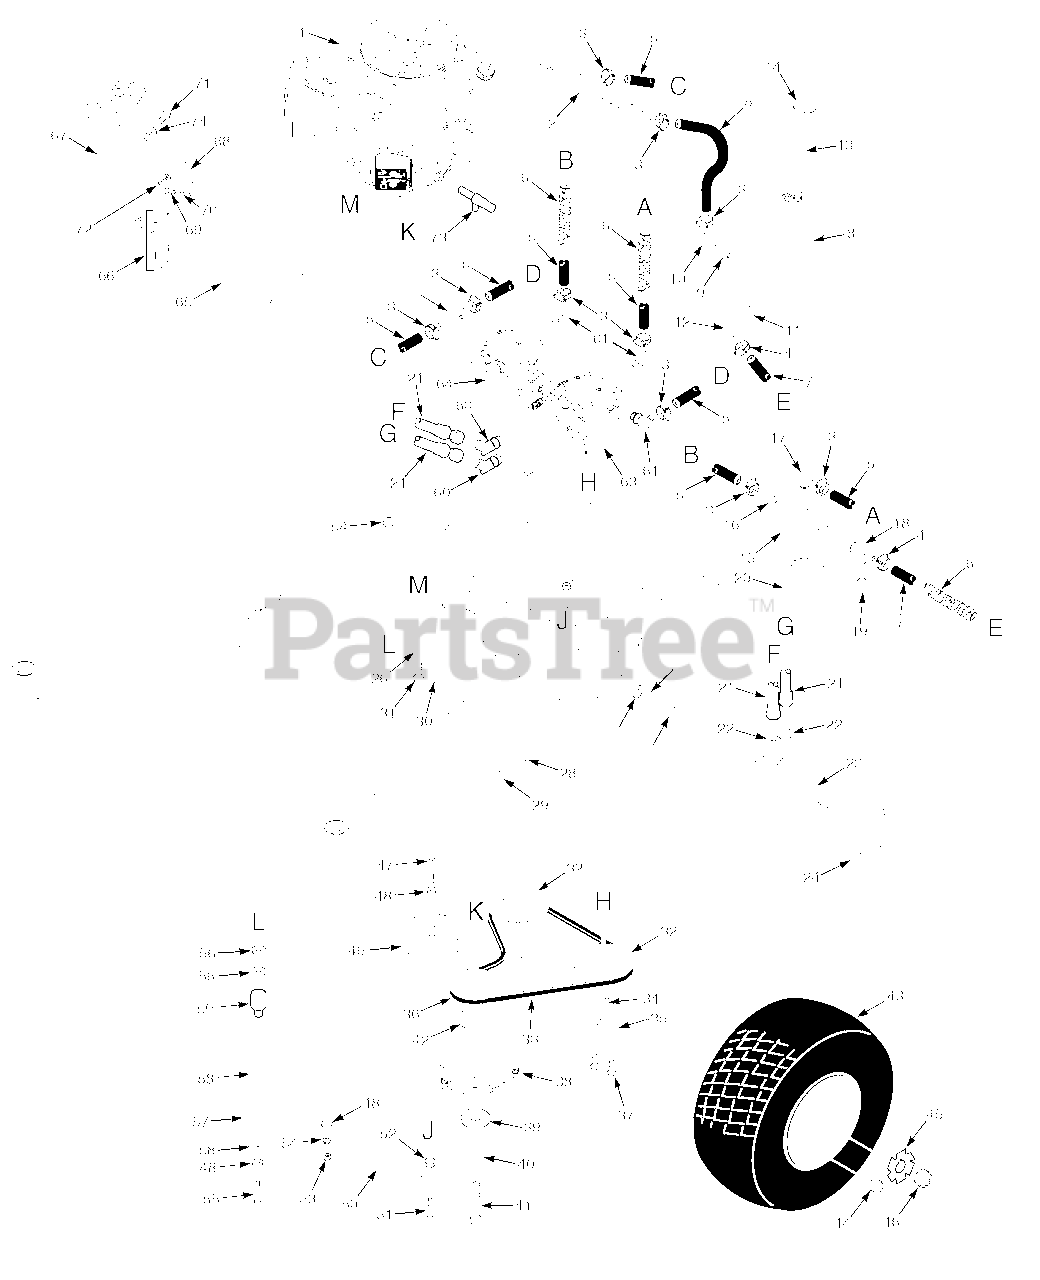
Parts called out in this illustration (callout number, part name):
1	Engine, 20hp Kawasaki FX
2	Cooler, Transmission
3	Clamp, .69 Max Dia.
4	Clamp, .87 Max Dia.
5	Hose, 3/8 Pushlock
6	Heatshield, Flexible
7	Hose, 1/2 Pushlock
8	Hydraulic Tank Assy.
9	Bushing, .56 Dia, Viton
10	Fitting, 90 Degree - .38 Hose
11	Bushing, .78 Dia. Viton
12	Fitting, 90 Degree - .50 Hose
13	Insert, Filler Neck
14	Cap, Hydraulic Tank
15	Filter Head
16	Fitting
17	Elbow, 90 Degree
18	Tee Fitting, 3/4 O-Ring
19	Cap, 3/4" JIC
20	Oil Filter
21	Hose Assembly
22	Fitting, Union 1/2 x 5/8
23	Wheel Motor, Hydro-Gear
24	Wheel Hub Assembly
25	Bolt, Hex Head 3/8-16 x 1"
26	Lockwasher, 3/8" Spring
27	Flatwasher, 3/8-.406 x .812 x .065
28	Nut, Serrated Flange 5/16-18
29	Bracket, Anti-Rotation (36")
30	Bolt, Carriage 5/16-18 x 1"
31	Bolt, Hex Head 3/8-16 x 1-1/4"
32	Pulley, 5.45 OD Tapered Bore
33	Belt, Pump Drive
34	Key, 5 x 5 x 25mm
35	Tapered Hub, 15mm Bore
36	Pulley, 4.75 OD - 1.125 Bore
37	Bolt, Hex Head 1/4-20 x 1" Gr. 8
38	Clutch w/Tag
39	Flatwasher, 7/16-.469 x 1.75 x .25
40	Lockwasher, 7/16" Spring
41	Bolt, Hex Head 7/16-20 x 2-1/4" Patch
42	Key, 1/4 x 1/4 x 3-1/2"
43	Wheel Assy., 18 x 7-8 (36)
43	Wheel Assy., 20 x 10.5-8
44	Wheel Nut
45	Lockwasher, Wheel Motor
46	Hex Castle Nut, Wheel Motor
47	Bolt, Hex Head 3/8-16 x 2-3/4"
48	Flatwasher, 3/8-.391 x .938 x .105 HD
49	Pulley, 4-1/2" Idler
50	Spring, Transmission
51	Bolt, Hex Head 3/8-16 x 3"
52	Nut, Serrated Flange 3/8-16
53	Nut, Center Lock 3/8-16
54	Nut, Elastic Stop 3/8-16
55	Bolt, Hex Head 3/8-16 x 3-1/4"
56	Flatwasher, 3/8-.375 x 1-1/2 x .059
57	Idler Arm Assy
58	Bearing
59	Idler Pivot, Long
60	Elbow, 45 Degree
61	Elbow, 90 Degree
62	Fitting, Tee
63	Pump, LH
64	Pump, RH
65	Exhaust Manifold, SVR
66	Clamp, Muffler
67	Muffler
68	Bracket, Muffler
69	Bolt, Hex Head M8 - 1.25 X 16
70	Lockwasher, 5/16" Spring
71	Bolt, Head Head 5/16-18 x 1"
72	Nut, 5/16-18
73	Oil Drain
74	Flatwasher, 5/16-.344 x .688 x .065
